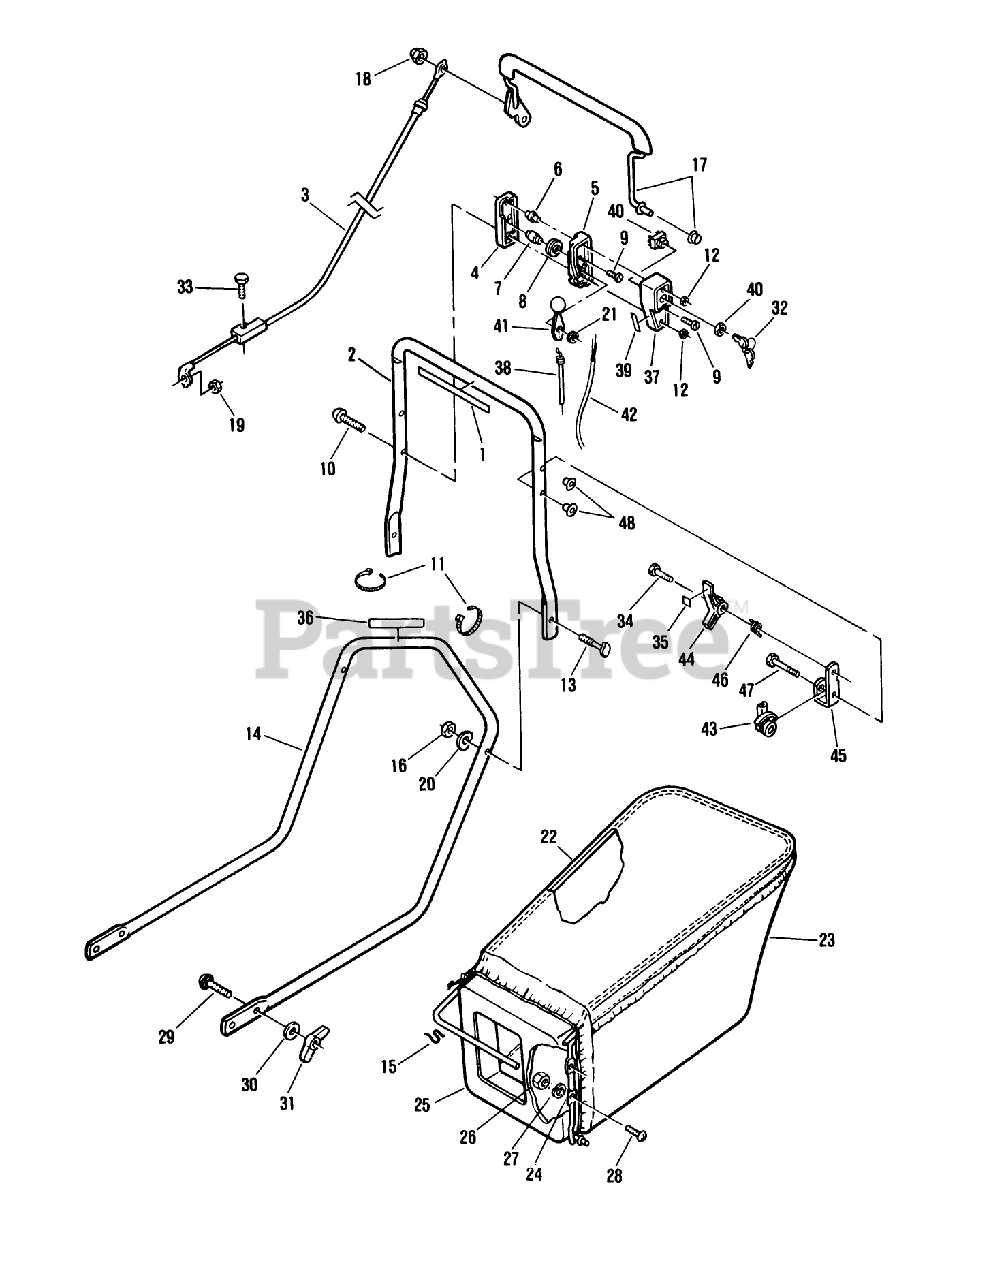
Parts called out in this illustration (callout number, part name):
3	CONTROL CABLE WES
6	COLUMN
7	PIN SKF
8	PULLEY PL
9	SCREW
10	SCREW
12	NUT C/LOCK E
15	S CLIP ARDEN
16	NUT-LOCK F
18	NUT ACORN
19	LOCKNUT E
20	WASHER-CURVED
21	WASHER-SPRING
22	HANGER BAG TROX
25	BAG ADAPTOR PL
26	LOCKNUT E
27	WASHER
30	WASHER
31	NUT-WING
33	SCREW-HH
38	CABLE TH'TTLE WES
41	LEVER&KNOB AY WES
47	BOLT QUALITY
